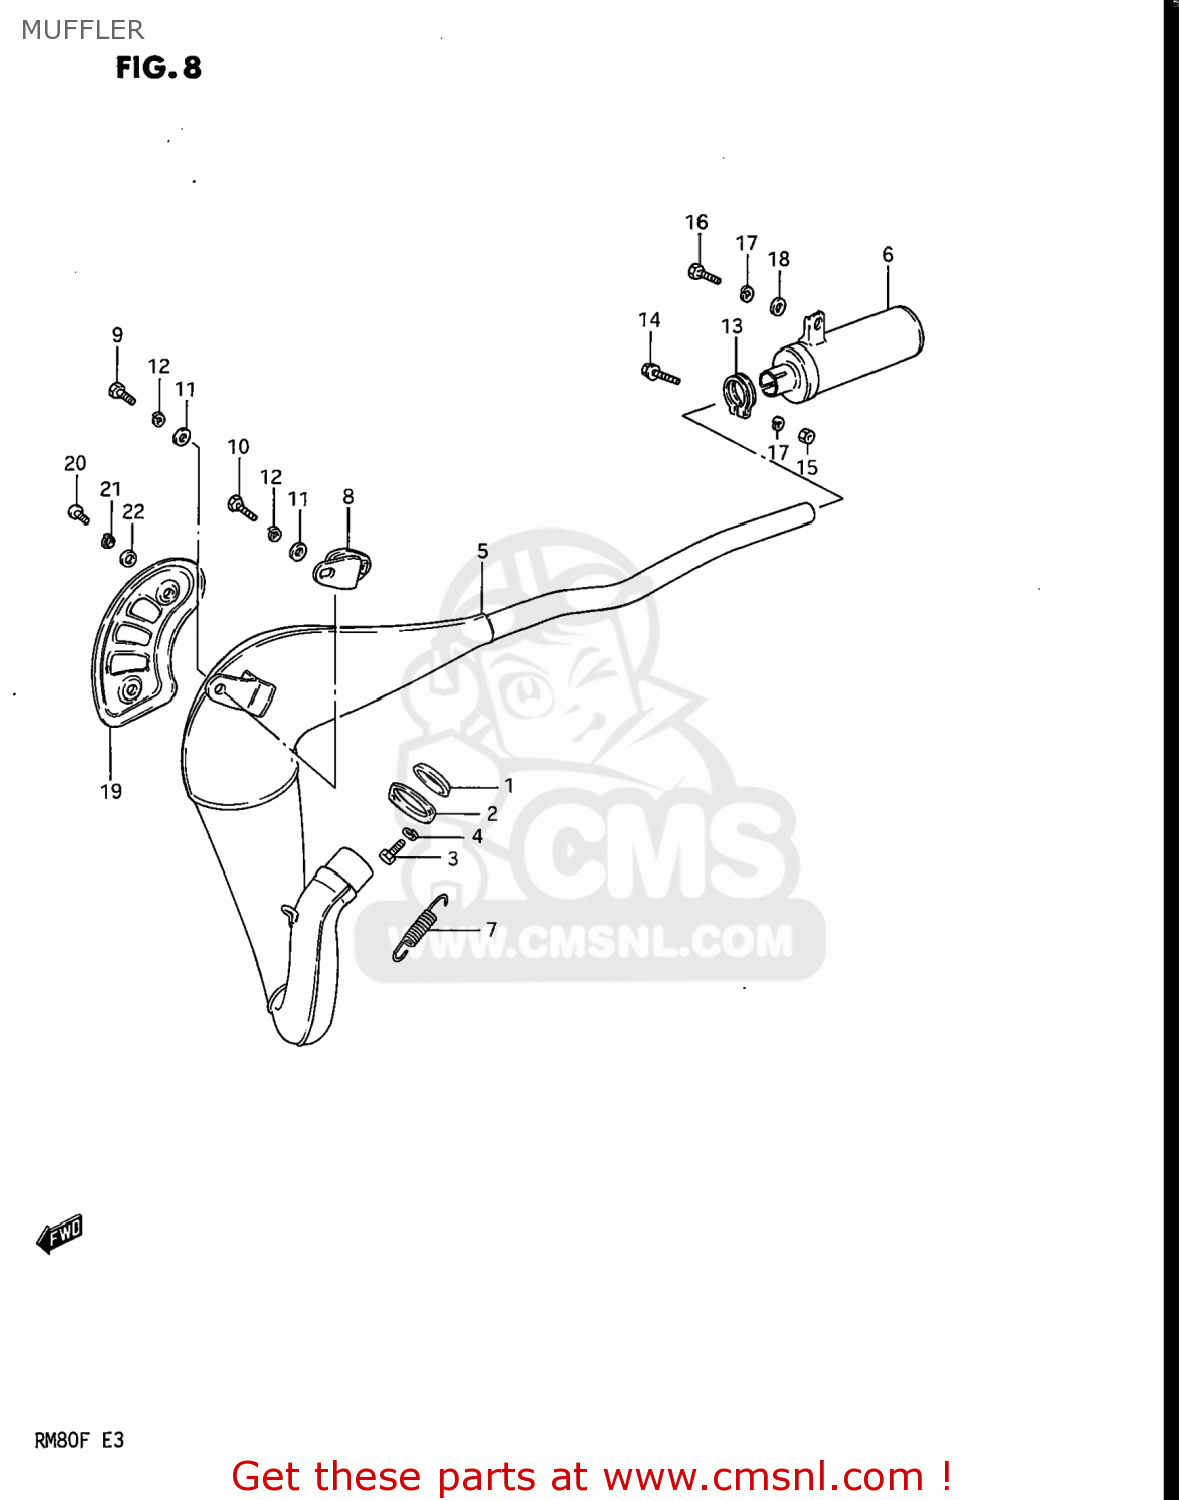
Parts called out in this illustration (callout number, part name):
1	GASKET,EXHAUST PIPE (NAS)
2	CLAMP,EXHAUST PIPE
3	BOLT 6X16
4	LOCK WASHER
5	BODY,MUFFLER
6	BODY,MUFFLER
7	SPRING
8	DAMPER,MUFFLER SUPPORT
9	BOLT
10	BOLT, UPPER
11	WASHER
12	LOCK WASHER
13	CLAMP,EXHAUST
14	BOLT
15	NUT
16	BOLT
17	LOCK WASHER
18	WASHER
19	COVER,MUFFLER
20	SCREW
21	WASHER,LOCK
22	WASHER
